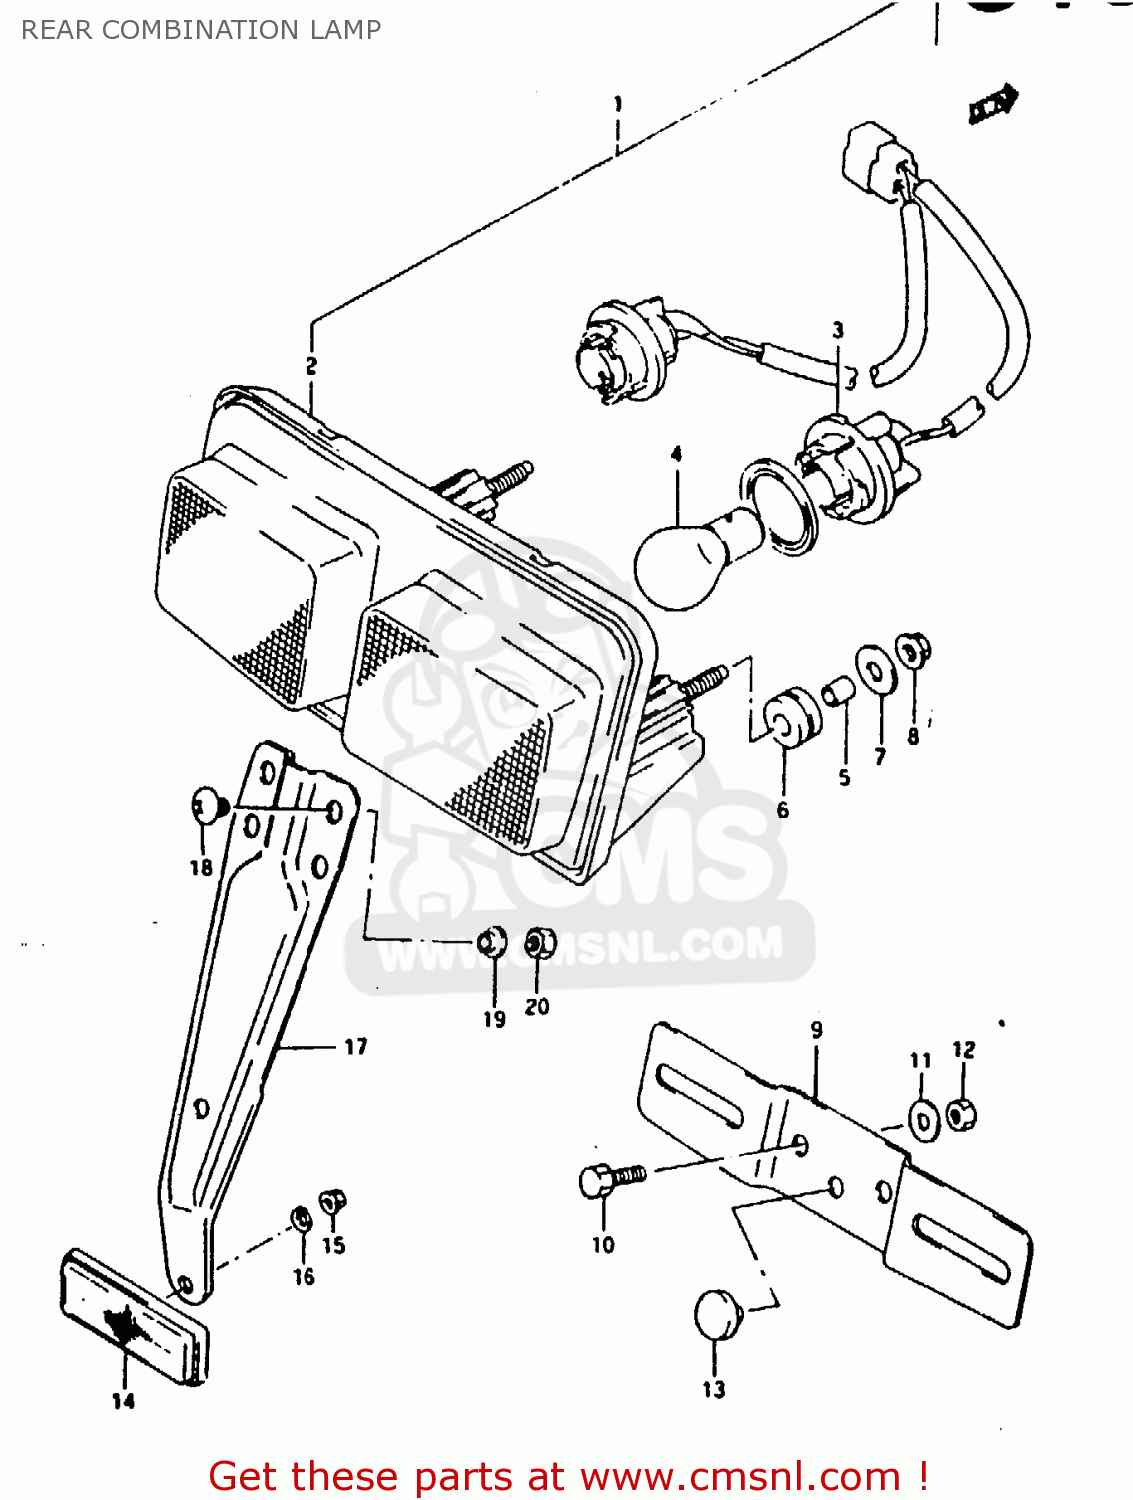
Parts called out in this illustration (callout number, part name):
1	LAMP ASSY,RR C
2	LAMP UNIT
3	SOCKET,RR COMB
4	BULB(12V21/5W)
5	SPACER (6.1X8X9.5)
6	CUSHION
7	WASHER(6.5X18X1)
8	NUT
9	PLATE,RR LICENSE
10	BOLT
11	WASHER,COVER,FRONT
12	NUT
13	CUSHION
14	REFLECTOR ASSEMBLY,REAR
15	NUT
16	WASHER
17	BRACKET, REAR REFLECTOR
18	SCREW 6X12
19	WASHER
20	NUT
